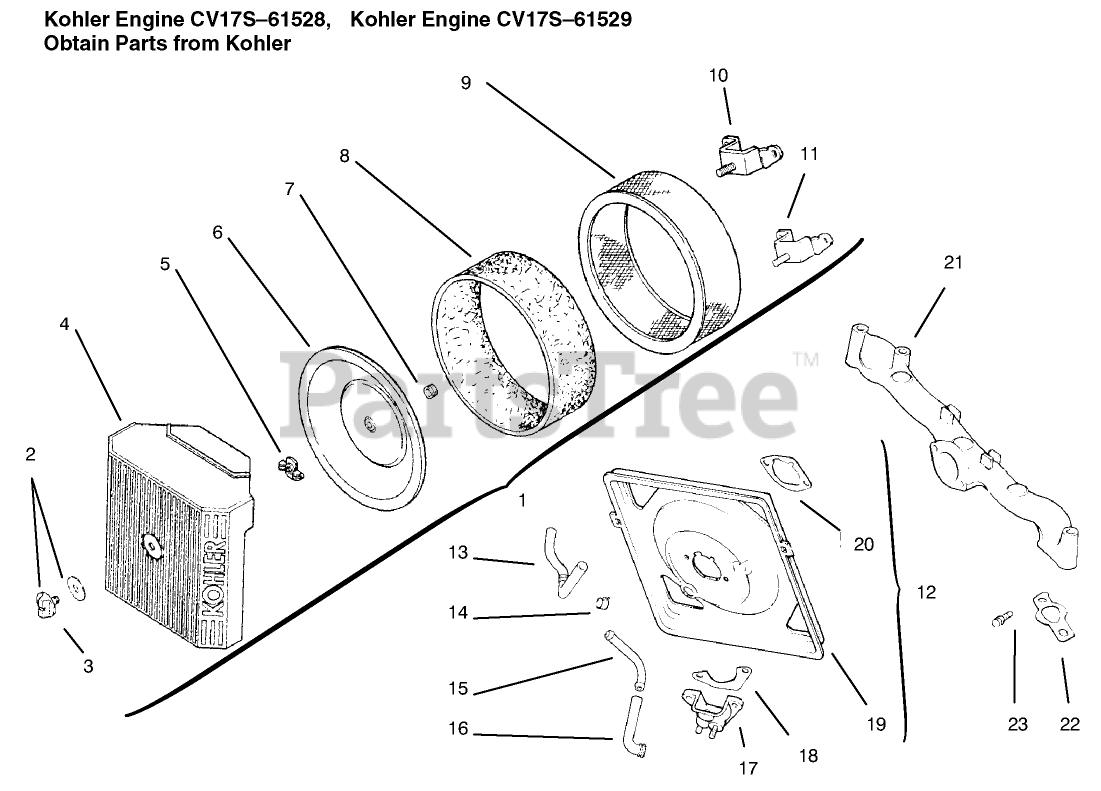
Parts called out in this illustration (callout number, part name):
1	Kit-Air Cleaner Cover
2	Kit-Knob w/Gasket
3	Knob-Cover
4	Cover-Air Cleaner
5	Nut-Wing
6	Cover-Inner Air Cleaner
7	Seal-Air Intake (Only On: 72103)
8	Element-Precleaner
9	Element-Air Cleaner
10	Bracket-Air Cleaner
11	Bracket-Air Cleaner
12	Kit-Air Cleaner Base
13	Hose-Breather
14	Clamp
15	Fitting
16	Hose-Breather
17	Cup-Fuel Spitback
18	Gasket-Fuel Spitback Cup (Only On: 72103, 72083)
19	Base-Air Cleaner
20	Gasket-A/C Base (Only On: 72103, 72083)
21	Manifold-Intake (Only On: 72103)
22	Gasket-Intake Manifold
